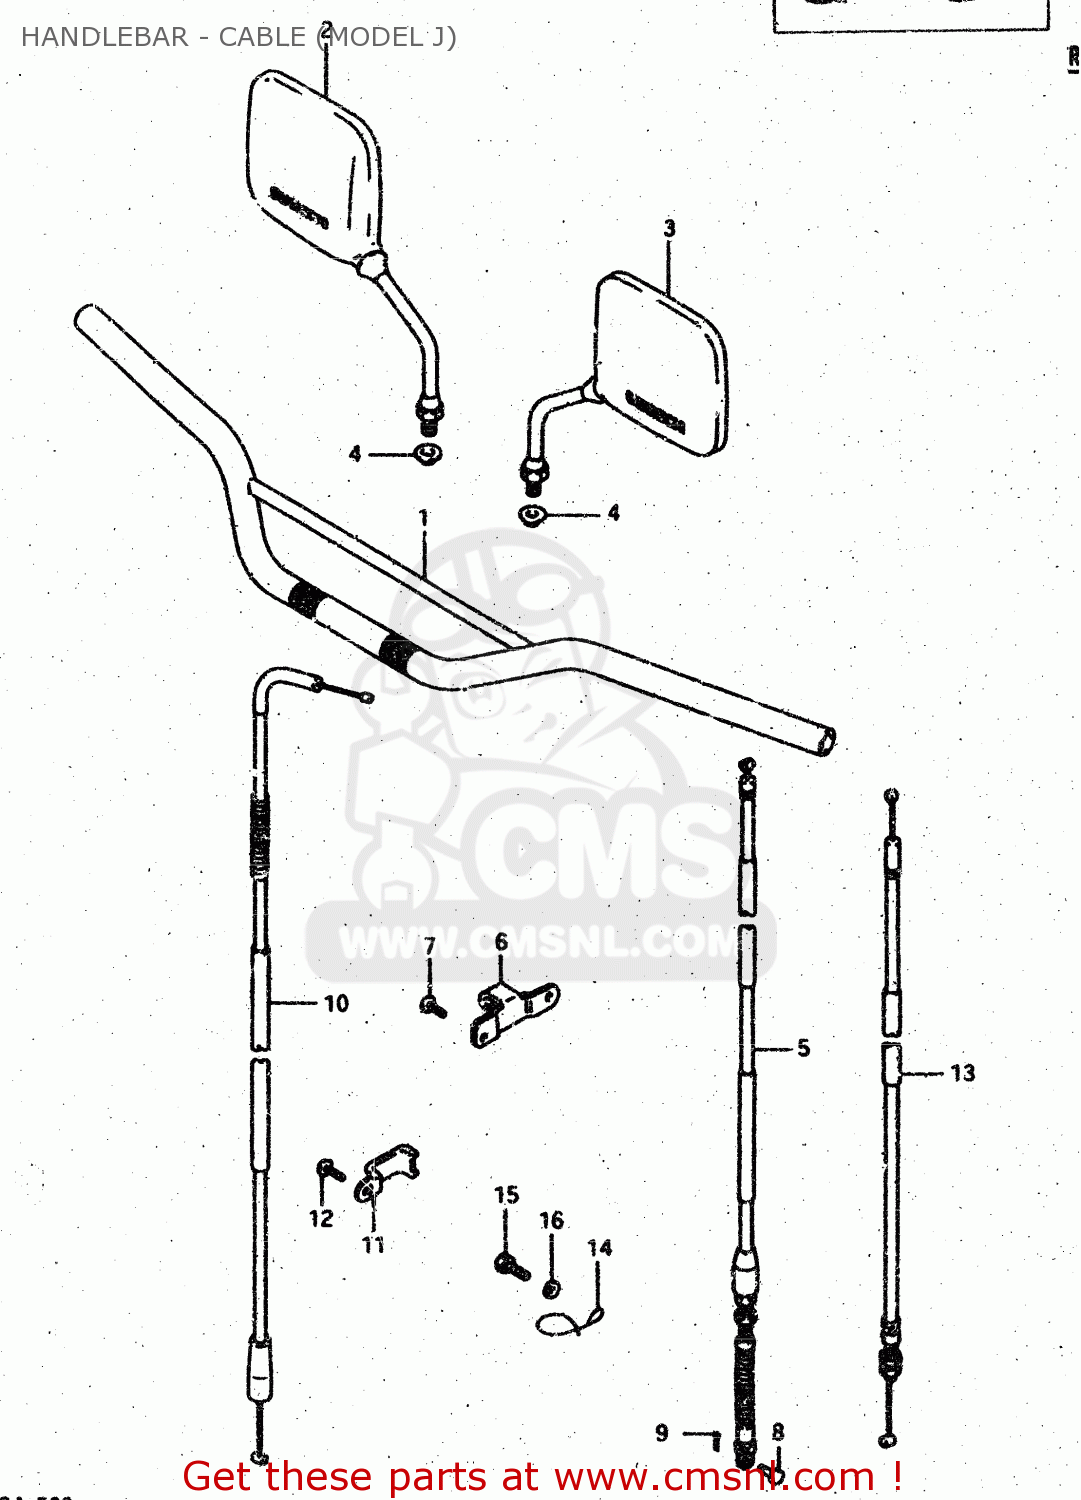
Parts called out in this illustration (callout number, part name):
1	HANDLEBAR
2	MIRROR ASSEMBLY,REAR VIEW
3	MIRROR ASSEMBLY,LEFT
4	WASHER
5	CABLE ASSY,CLUTCH
6	STOPPER,CLUTCH CABLE
7	SCREW
8	PIN(L:13)
9	PIN
10	CABLE ASSEMBLY,THROTTLE
11	CLAMP
12	SCREW
13	CABLE ASSY,DECOMP
14	GUIDE
15	BOLT
16	WASHER,LOCK
